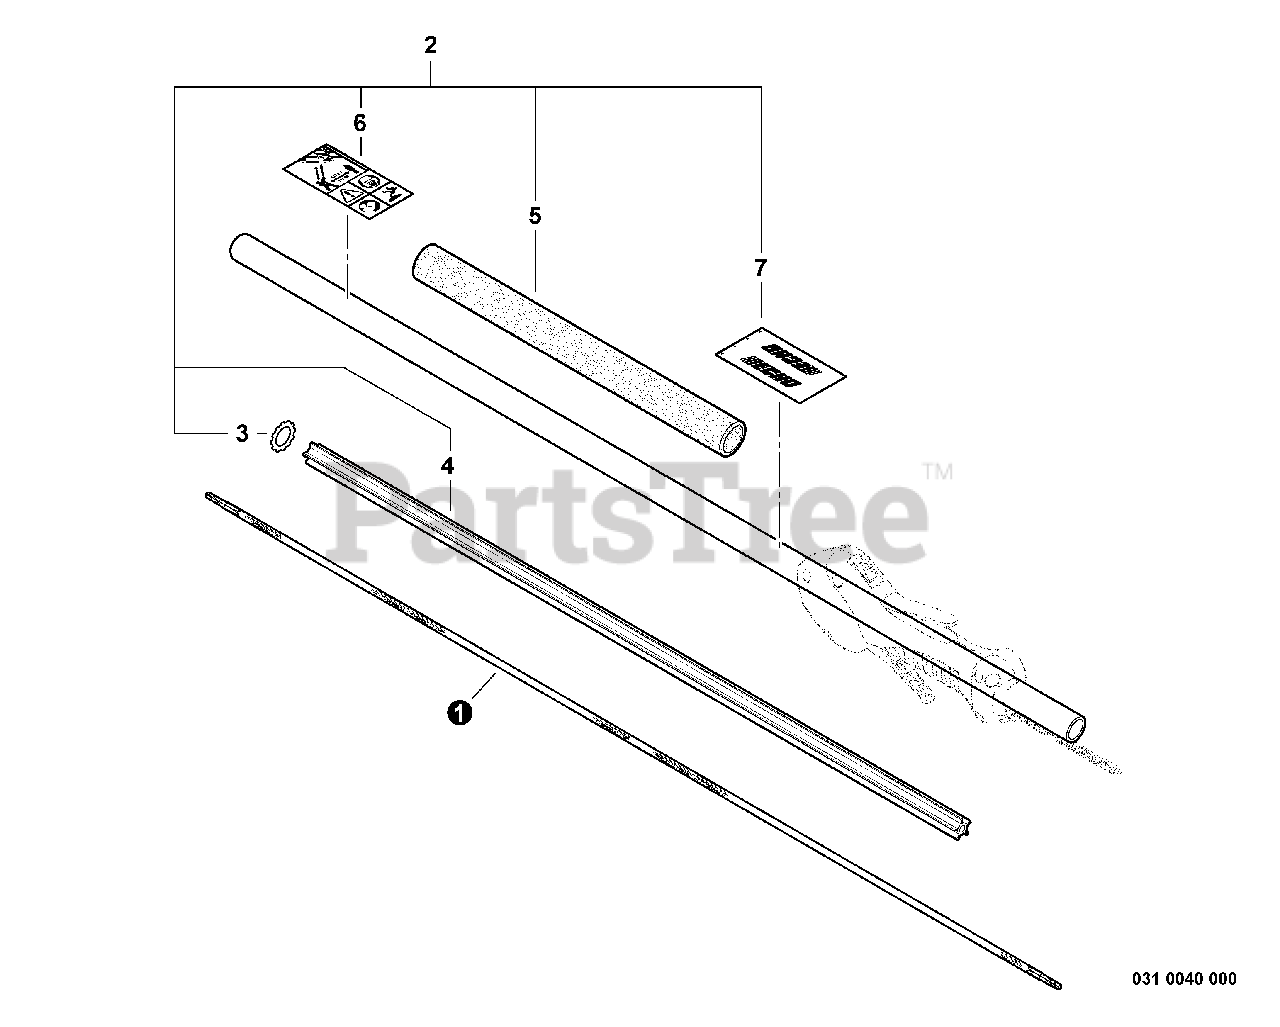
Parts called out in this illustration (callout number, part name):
1	DRIVESHAFT - FLEXIBLE
2	MAIN PIPE ASSY
3	LOCKWASHER - EXTERNAL
4	LINER - FLEXIBLE
5	GRIP, HANDLE - FRONT
6	LABEL - CAUTION
7	LABEL - HANDLE LOCATION
